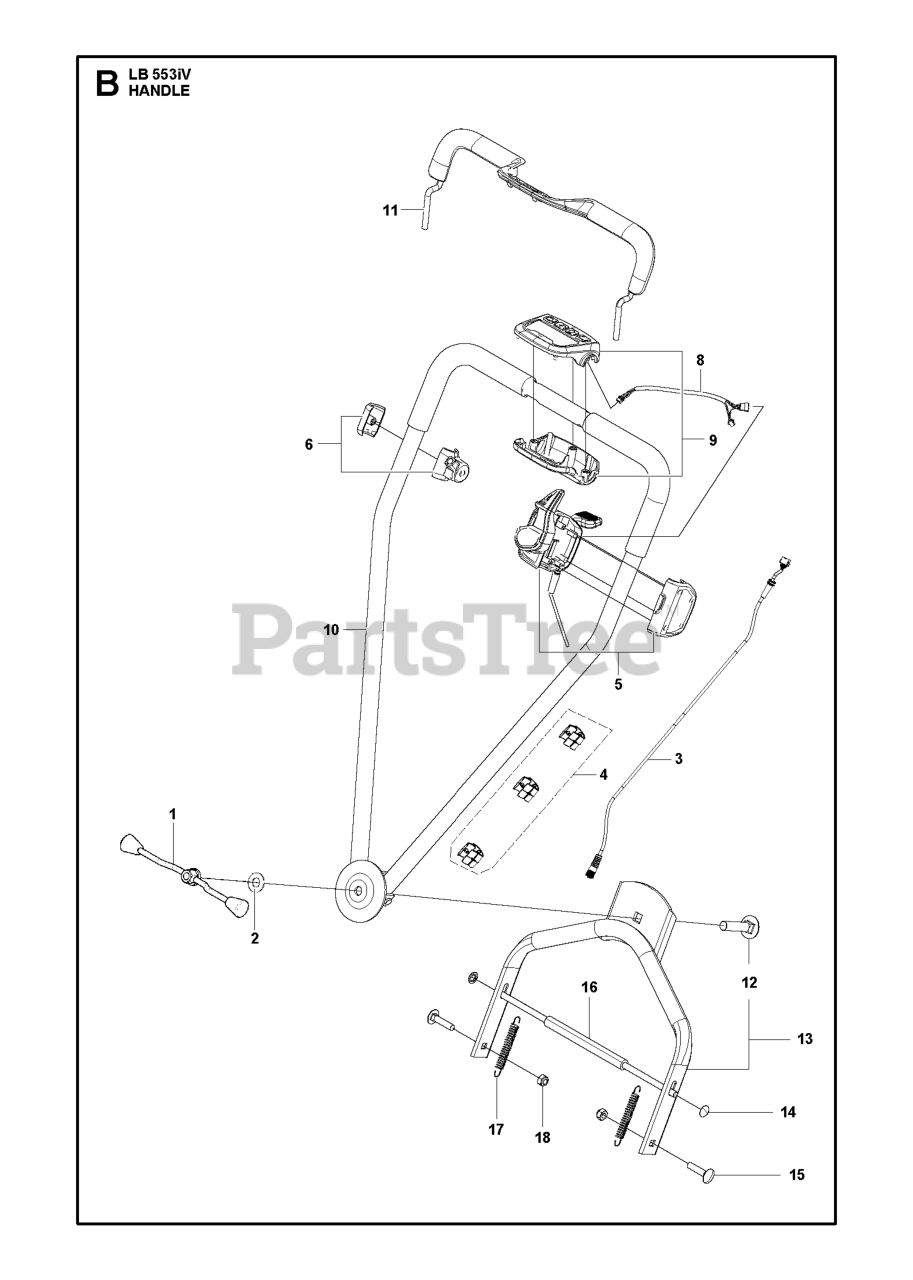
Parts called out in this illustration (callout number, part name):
6	BAIL ARM ASSY SPARE PART ASSY
14	WASHER STARLOCK WITH CAP
18	LOCKNUT M8
